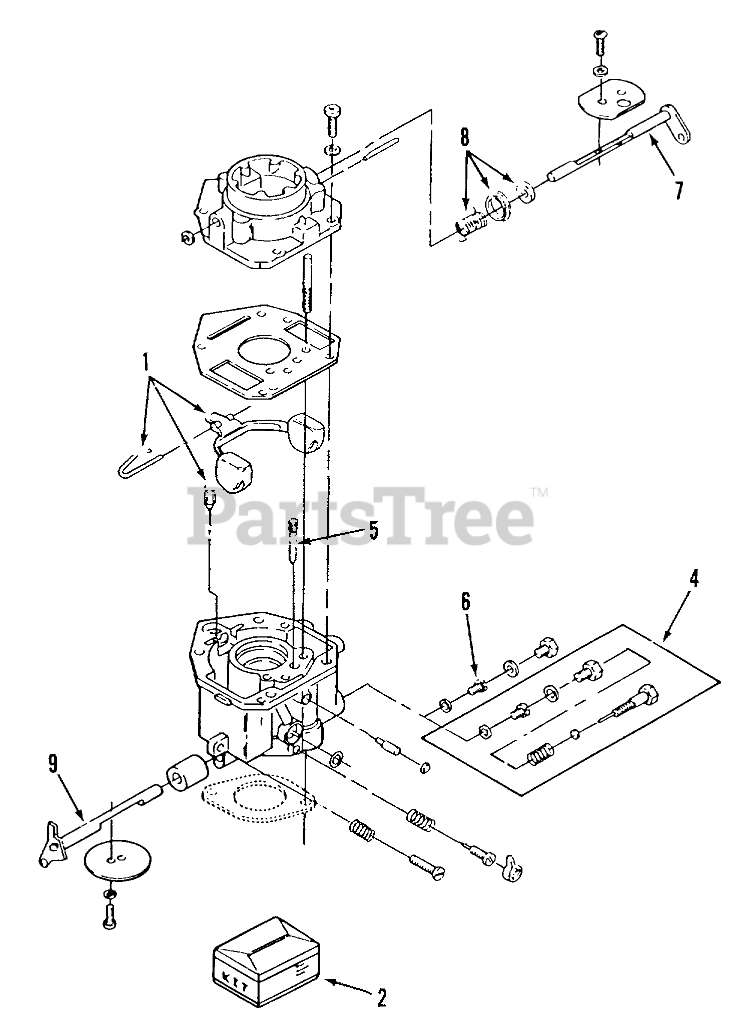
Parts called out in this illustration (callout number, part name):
1	Float Kit (includes Float, Pin and Valve)
2	Repair Kit (includes Screw and Plug package, Gasket package, Float Valve, Idle Adjustment Needle and Spring, Mounting Gaskets, Idle Limit Cap)
4	Variable Jet Kit-Optbnal (High Altitude Application Includes Power Jet and Gasket, Retainer, Power Needle Spring, Power Needle and Power Plug Gasket)
5	Idle Jet
6	Power Jet
7	Choke Shaft-Kit (includes Choke Valve, Valve Set Screw and Air Filter)
8	Choke Lever-Kit (includes Choke lever Ring, Choke Spring and Choke Collar)
9	Throttle Shaft-Kit (includes Valve Set Screw, Air Filter and Throttle Valve)
